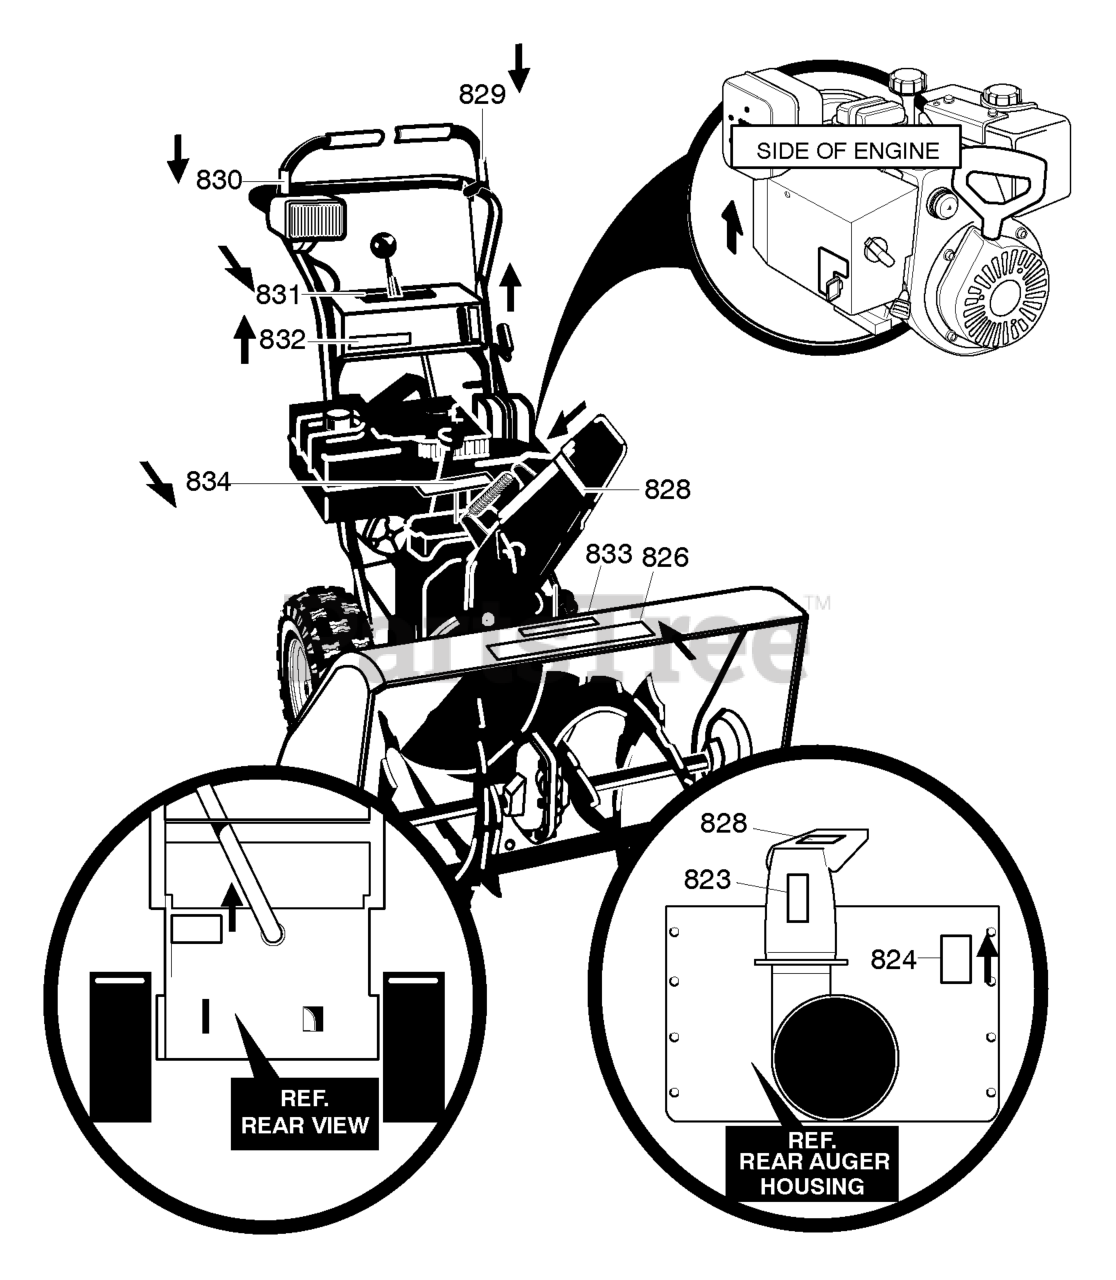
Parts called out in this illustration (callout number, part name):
823	DECAL, DANGER CHUTE HAND
824	DECAL, DANGER FOOT
826	DECAL, CRAFTSMAN 10.5/30
828	DECAL, THROWN OBJECTS
829	DECAL, DRIVE CLUTCH
830	DECAL, AUGER CLUTCH
831	DECAL, GEAR SELECTOR
832	DECAL, CRAFTSMAN
833	DECAL, CLEAN & CLEAR BRUSH
834	DECAL, TOOLBOX INFORMATION
